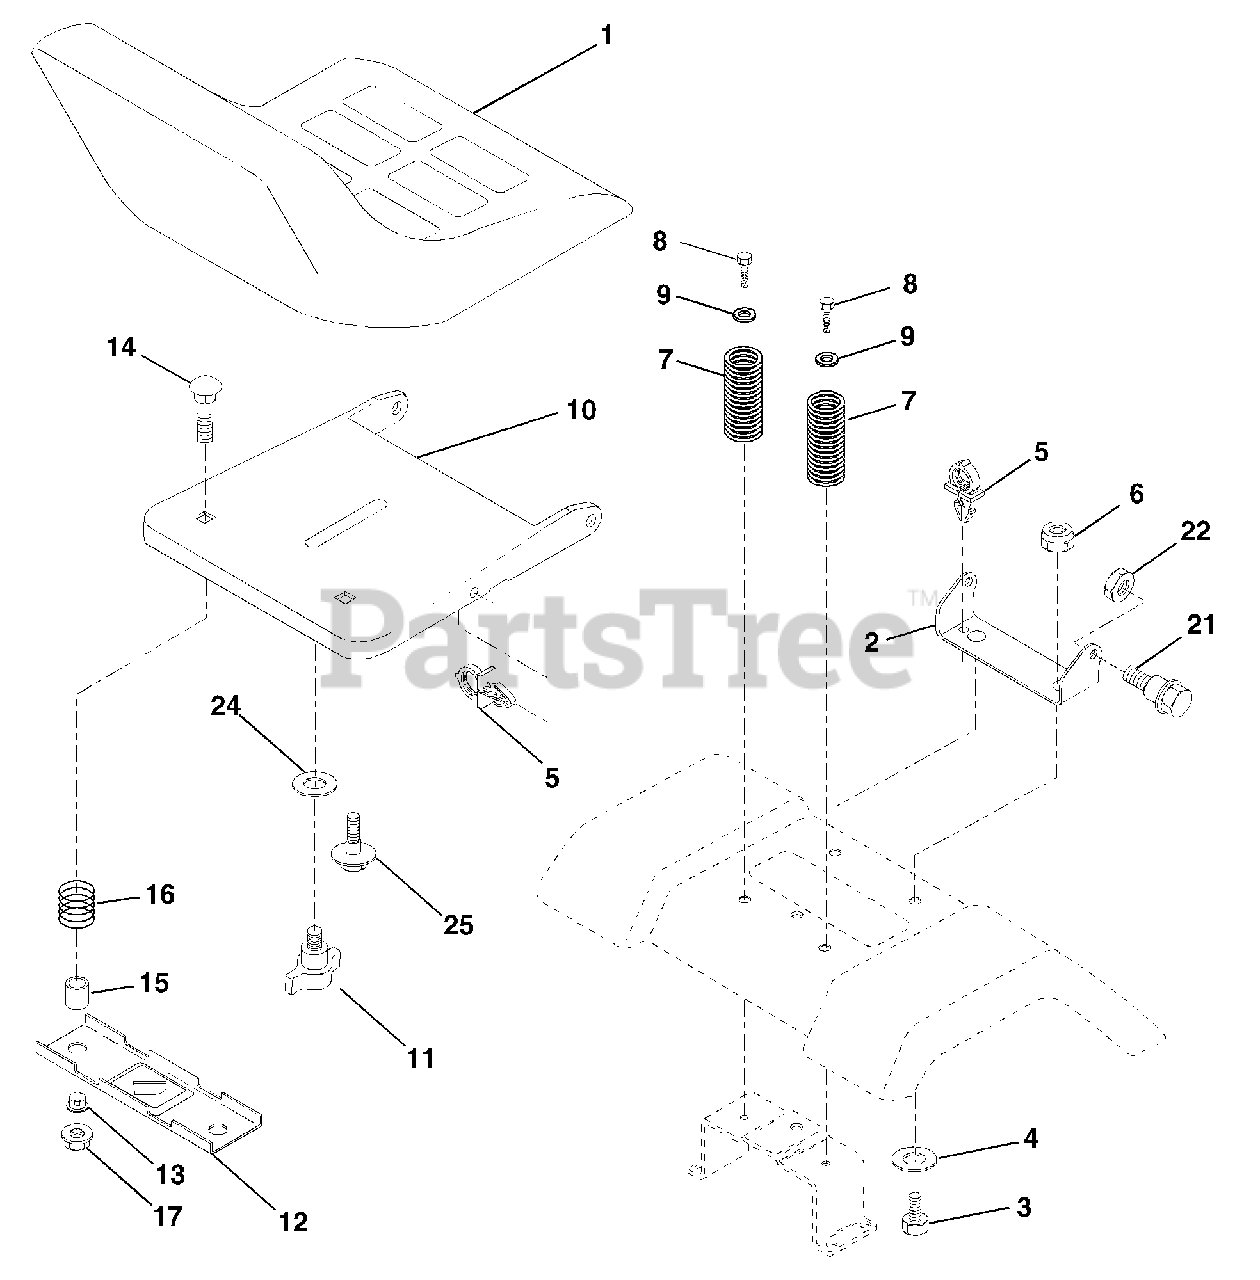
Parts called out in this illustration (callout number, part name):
2	Bracket Pvt St
3	Bolt Fin Hex 3/8-16unc x 1
4	Washer Flat 13/32 x 1 x 10 Ga
5	Clip Push-In Hinged
6	Locknut Hex W/Wsh 3/8-16
7	Spring Seat Cprsn 2 250 Blk
8	Screw 3/8-16 x 1
9	Washer 13/32 x 1 x 14 Ga
10	Pan Seat
11	Knob Seat Adj. Wingnut
12	Bracket Mounting Switch
13	Bushing Snap Blk Nyl 50 Id
14	Bolt Rdhd Sht 1/4-20x1-1/2
15	Spacer Split 28x 96 Yel Zinc
16	Spring Cprsn 1 27 Blk Pnt
17	Nut Lock 1/4 Lge Flg Gr 5
21	Bolt Shld 5/16-18 Unc
22	Nut Lock Hex W/Ins 5/16-18
24	Washer 17/32 x 1-3/16 x 12 Ga
25	Bolt Shoulder 5/16-18 x 62
